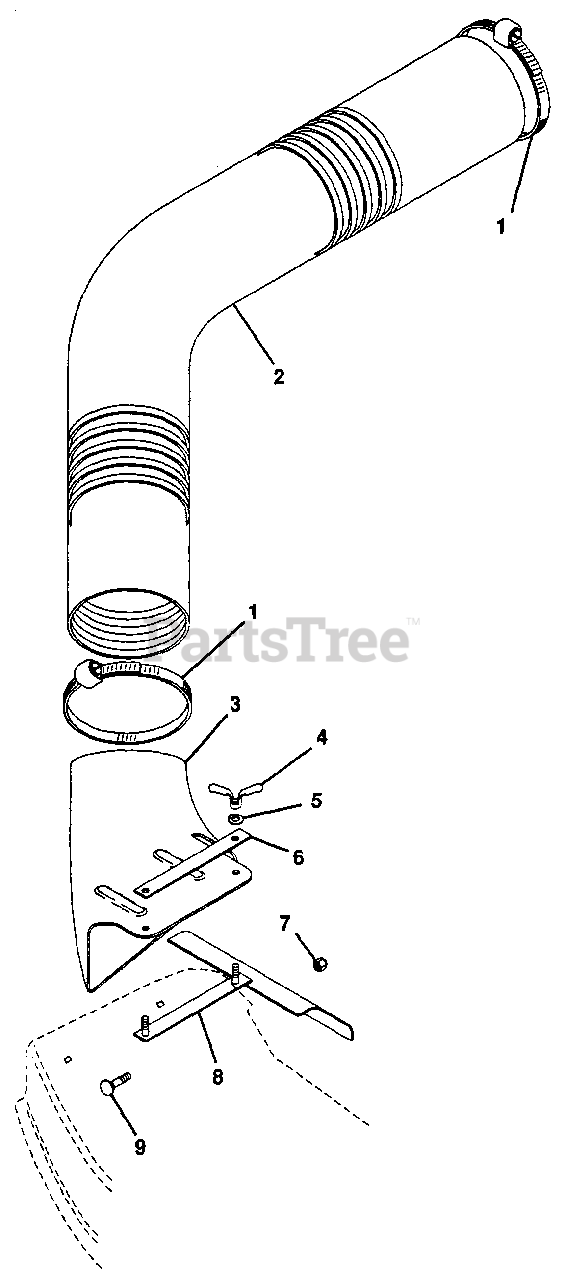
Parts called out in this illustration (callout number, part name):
1	Clamp
2	Hose, Mower to Blower
3	Boot, Discharge 50"
4	Nut, Wing 3/8-16
5	Washer, Lock 3/8 Reg.
6	Plate, 50" Boot
7	Nut, Lock 3/8-16
8	Weldment, 50" Boot Clamp
9	Bolt, Carriage 3/8-16x.75
